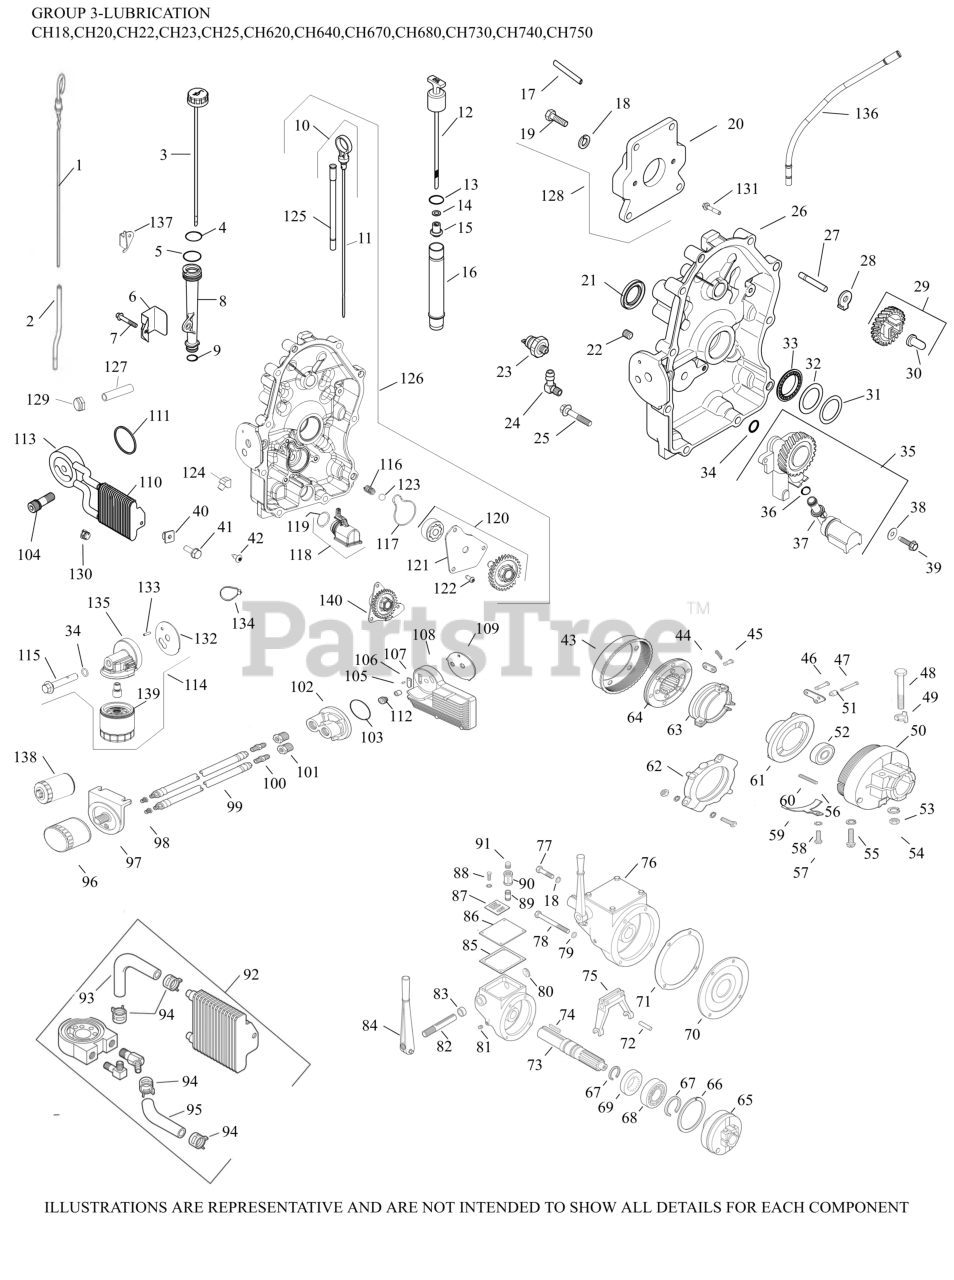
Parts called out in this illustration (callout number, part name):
10	KIT, DIPSTICK/DIPSTICK TUBES
23	SENSOR, OIL PSI
24	CONNECTOR, 90 DEG. HOSE
25	SCREW, FLG M8X1.25X45
27	SHAFT, GOVERNOR GEAR
28	TAB, LOCKING
29	KIT, GOVERNOR GEAR W/PIN
30	PIN, GOVERNOR REGULATING
34	O-RING
35	PUMP ASSEMBLY, OIL-USE 24 393 53-S
36	O-RING, OIL PICK-UP
37	PICK-UP, OIL
38	WASHER, FLAT 6 MM
39	SCREW,FLG THD FRM M6X1.0X25-(#25086395S)
40	NUT, PLASTIC - BLACK
42	SCREW, TAPPING
93	KIT, HOSE 140MM
96	OIL FILTER
104	NIPPLE, OIL FILTER
110	COOLER, OIL & DIVERTER ASSEMBLY
111	O-RING, OIL COOLER
113	ADAPTER, OIL FILTER (CV EFI)
116	SPRING, COMPRESSION
117	SEAL, OIL PUMP COVER
118	PICK-UP ASSEMBLY, OIL
119	O-RING, OIL PICK-UP
120	PUMP ASSEMBLY, OIL
121	COVER, OIL PUMP
122	SCREW, BUTTON HEAD
123	PRESSURE RELIEF BALL
126	KIT, CLOSURE PLATE ASSY
126	CLOSURE PLATE USE 24 009 167-S
130	CLAMP, HOSE LOW PROFILE
131	SCREW, HEX FLANGE
